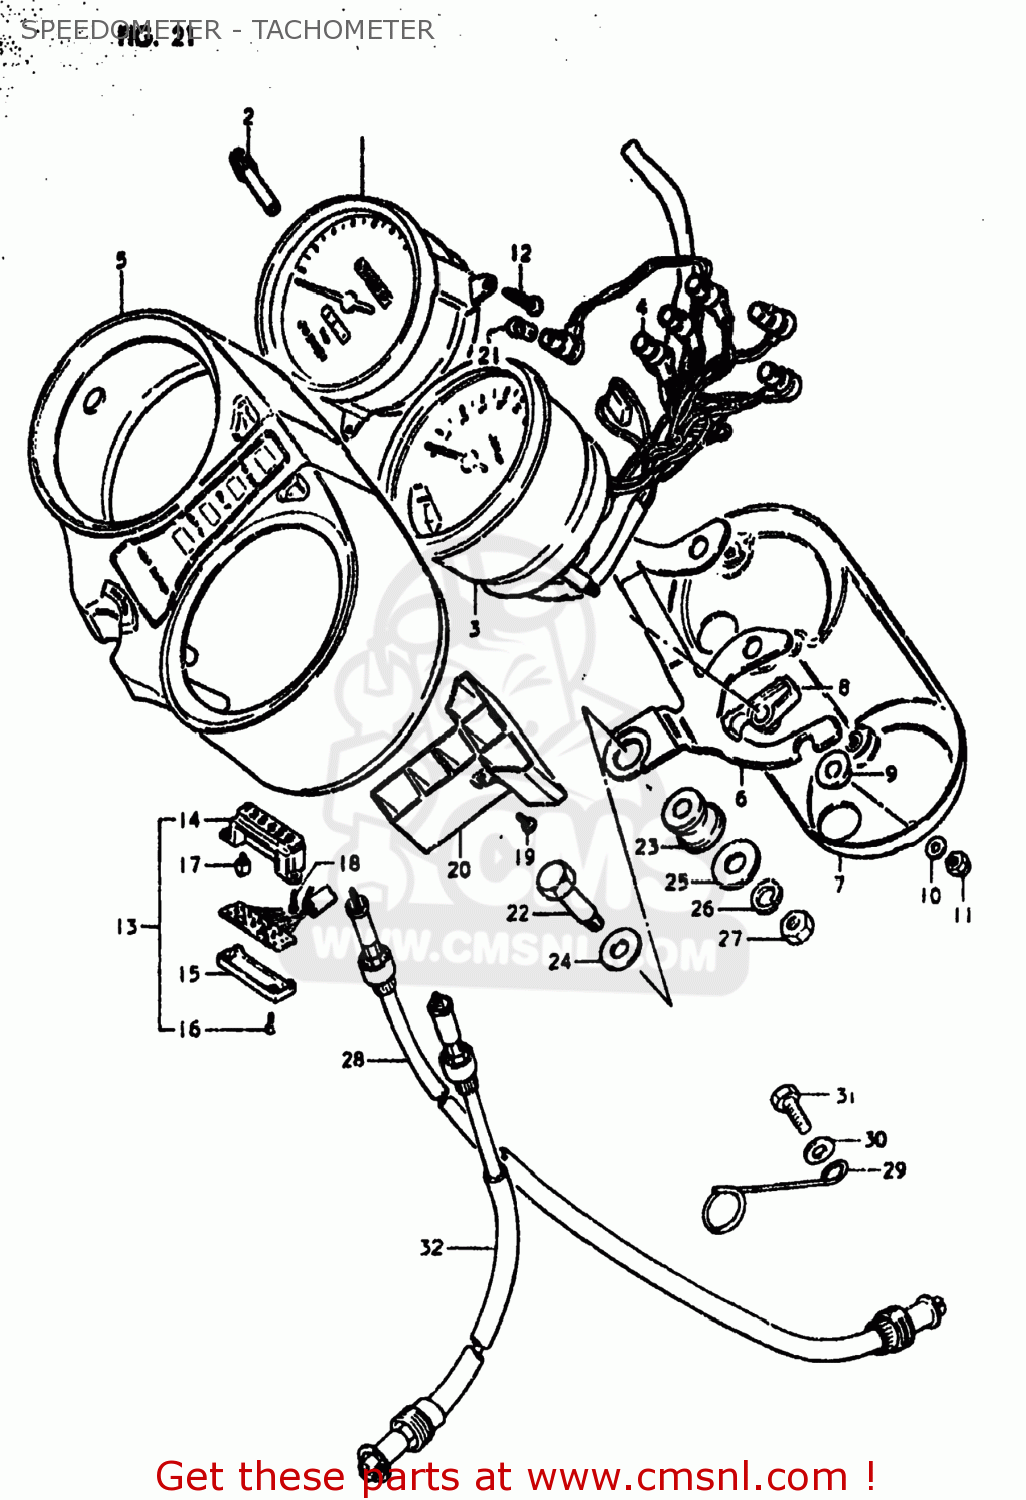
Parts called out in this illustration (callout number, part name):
1	SPEEDOMETER ASSEMBLY
2	KNOB
3	TACHOMETER
4	SOCKET,METER
5	CASE
6	BRACKET,COMBINATION METER
7	COVER,UNDER
8	CUSHION,METER (A)
9	CUSHION,METER (B)
10	WASHER
11	NUT
12	SCREW
13	INDICATOR ASSEMBLY,GEAR POSITION
14	CASE,GEAR INDICATOR
15	COVER,LWR
16	SCREW,GEAR INDICATOR
17	BULB(14V1.12W)
18	SCREW
19	SCREW
20	CASE,PILOT BULB
21	BULB(12V3.4W,STANLEY,A72A)
22	BOLT
23	CUSHION,METER
24	WASHER
25	WASHER (8.5X29X1.6)
26	LOCK WASHER
27	NUT
28	CABLE ASSEMBLY,SPEEDOMETER
29	GUIDE,SPEEDOMETER CABLE
30	WASHER
31	BOLT, UPPER
32	CABLE ASSEMBLY,TACHOMETER
